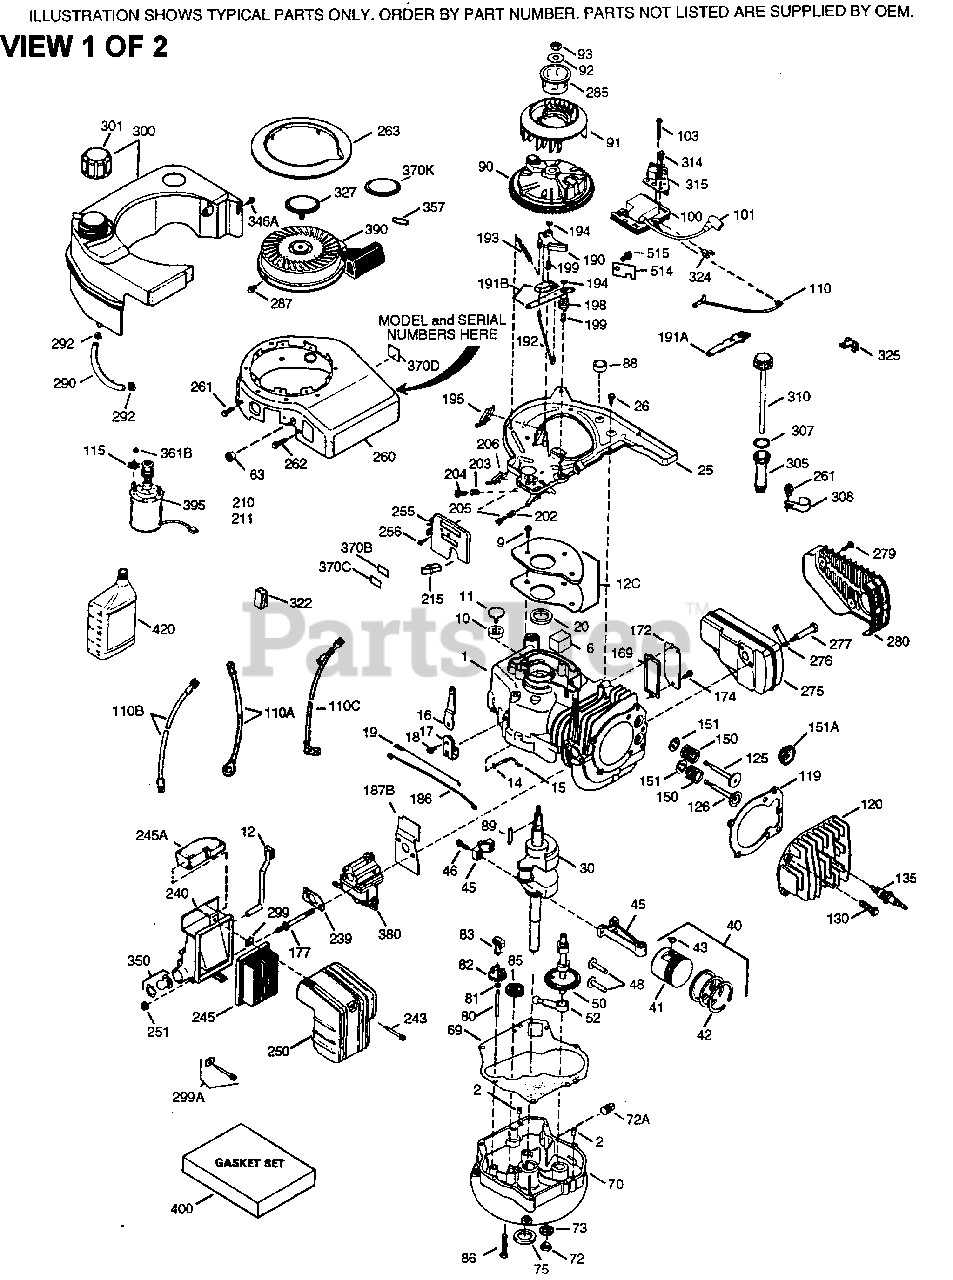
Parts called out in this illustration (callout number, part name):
1	"Cylinder (Incl. 2, 10, & 20)
2	Dowel Pin
6	Breather Element
9	Screw, 10-24 x 1/2"
10	Breather Valve Body
11	Check Valve
12	Breather Tube
12C	* Breather Cover & Gasket
14	Flat Washer
15	Governor Rod (Machined)
16	Governor Lever
17	Governor Lever Clamp
18	Screw, 8-32 x 5/16"
19	Governor Spring
20	Oil Seal
25	Blower Housing Baffle Ass'y. Incl.l95
26	Screw, 1/4-20 x 5/8"
30	Crankshaft Ass'y.
40	Piston,Pin,Ring Set (Std.)
40	Piston,Pin,Ring Set (.010 OS)
40	Piston,Pin,Ring Set (.020 OS)
41	Piston & Pin Ass'y.(Std.) (Incl. 43)
41	Piston & Pin Ass'y.(.010 OS)(Incl.43)
41	Piston & Pin Ass'y.(.020 OS)(Incl.43)
42	Ring Set (Std.)
42	Ring Set (.010 OS)
42	Ring Set (.020 OS)
43	Piston Pin Retaining Ring
45	Connecting Rod Ass'y. (Incl. 46)
46	Connecting Rod Bolt
48	Valve Lifter
50	Camshaft (MCR)
52	Oil Pump Ass'y.
62	Screw, 8-32 x 3/8" (Optional)
69	* Mounting Flange Gasket
70	Mounting Flange (Incl. 72 thru 85)
72	Oil Drain Plug
73	Drain Plug Gasket
75	Oil Seal
80	Governor Shaft
82	Governor Gear Ass'y. (Incl.81)
83	Governor Spool
85	Idler Gear
86	Screw, 1/4-20 x 1-9/16"
89	Flywheel Key
90	Flywheel
91	Flywheel Fan
92	Belleville Washer
93	Flywheel Nut
100	Solid State Ignition
101	Spark Plug Cover
103	Screw, Torx T-15, 10-24 x 1"
110	Ground Wire
119	* Cylinder Head Gasket
120	Cylinder Head
125	Exhaust Valve (Std.) (Incl. 151)
125	Exhaust Valve (1/32" OS)
126	Intake Valve (Std.) (Incl. 151)
126	Exhaust Valve (1/32" OS) (Incl. 151)
130	Screw, 5/16-18 x 1-1/2"
135	Resistor Spark Plug (RJ19LM) also ava ilable in Packaged Part #740081
150	Valve Spring
151	Lower Valve Spring Cap
169	* Valve Spring Box Gasket
172	Valve Spring Box Cover
174	Screw, 10-24 x 9/16"
177	Carburetor Mounting Stud
186	Governor Link
187	* Carburetor Mounting Spacer
190	Brake Lever Ass'y.
191B	Brake Control Lever
192	Brake Control Lever Link
193	Brake Spring
194	Retaining Ring
195	Terminal Ass'y.
198	Brake Control Lever Spring
199	Brake Lever Bushing
202	Compression Spring
203	Compression Spring
204	Screw, 5-40 x 7/16"
205	Screw, 6-32 x 21/32"
215	Control Knob
239	* Carburetor to Air Cleaner Gasket
240	Air Cleaner Body (Incl.239,299 & 350)
243	Screw, 10-32 x 2-3/32"
245	Air Filter (Paper) (also available in Packaged Part #740031B for model VLV only) (also available in Packaged Pa rt #740061C for model OH195)
250	Air Cleaner Cover
251	Lock Nut 1/4-20
255	Control Plate
256	Screw, 8-32 x 21/64"
260	Blower Housing
261	Screw, 1/4-20 x 11/16"
262	Screw, 1/4-20 x 1-1/2"
263	Recoil Ring
275	Muffler Ass'y.
276	Locking Plate
277	Screw, 5/6-18 x 2-11/32"
285	Starter Cup
287	Screw, 8-32 x 21/64"
290	Fuel Line
292	Fuel Line Clamp
299	"U" Type Nut Clip
300	Fuel Tank (Incl. 301)
301	Fuel Cap (Red)
305	Oil Fill Tube
307	"O" Ring
308	Fill Tube Clip
310	Dipstick
327	Starter Plug his)
346A	Screw, 10-32 x 35/64"
350	Primer
370	Instruction Decal
370D	Control Decal
380	Carburetor (Incl. 187 & 239)
390	Rewind Starter NOTE: This engine cou ld have been built with 590686 starte r. Refer to the design of the air int ake louvers for part identification. Individual starter parts do not inter change.
400	* Gasket Set (Incl. items marked PK in notes). Incl. part #'s 27234A (1), 3 6005A (1), 36032 (1), 36035 (1), 3604 8 (1), 36119 (1)
999	Summer Maintenance Kit (incl. Oil, Sp ark Plug, Air Cleaner, & Ultra Fresh)
